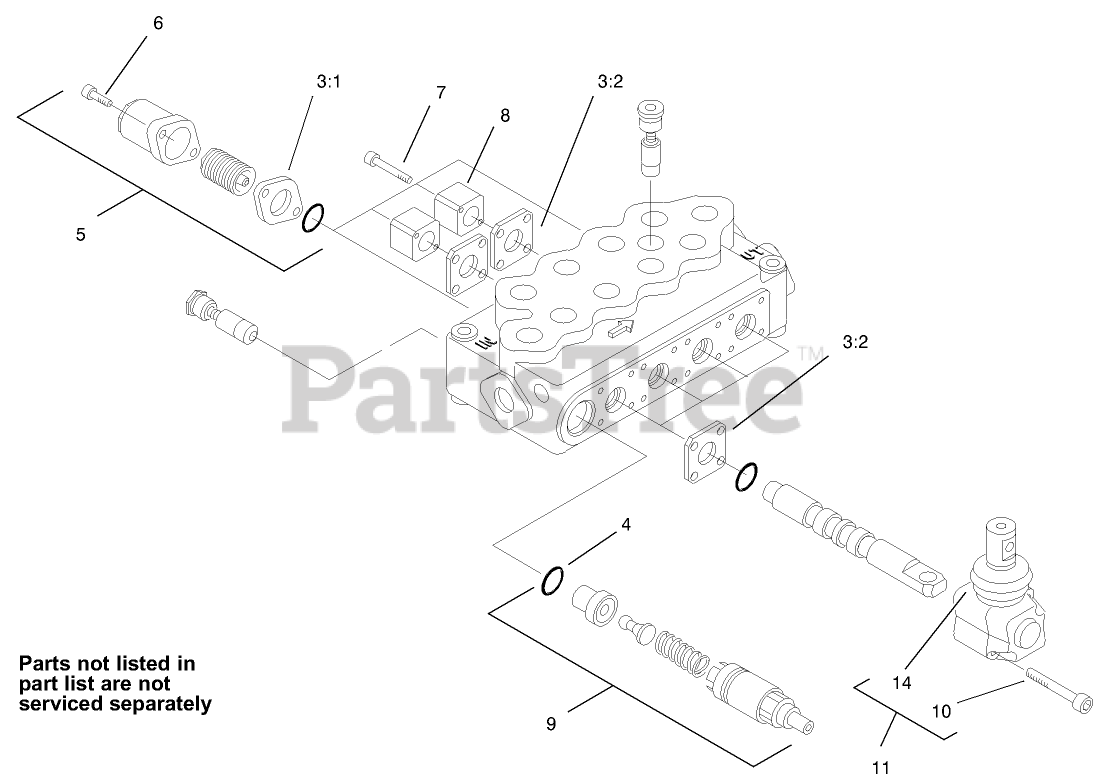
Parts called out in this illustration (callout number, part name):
3	SEAL KIT
3:1	GASKET
3:2	GASKET
5	HIGH FORCE SPRING KIT
6	SCREW-CAP, END
8	BLOCK-MOUNT, SWITCH
9	VALVE-RELIEF
11	OPERATOR ASM
